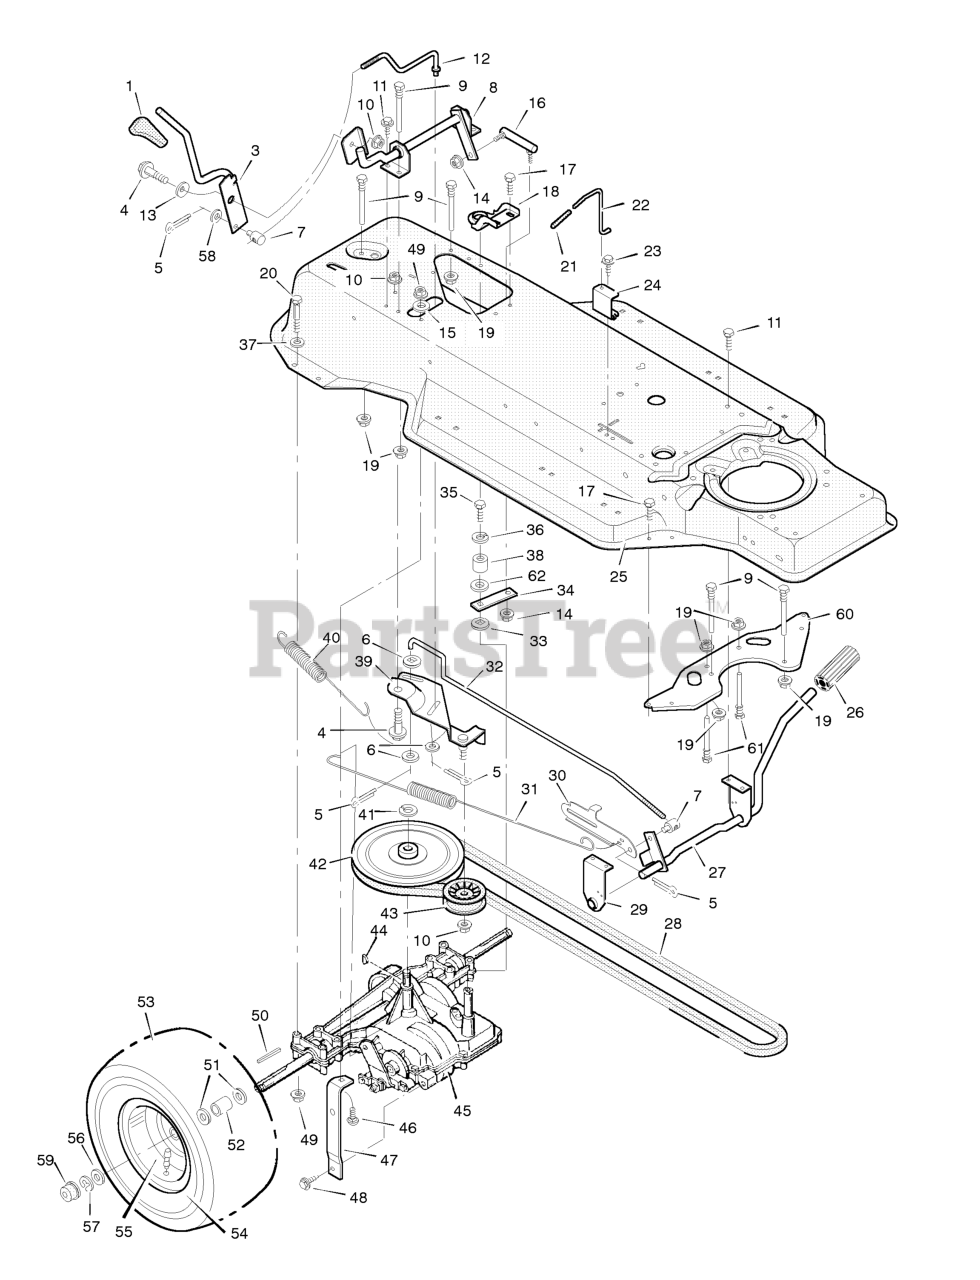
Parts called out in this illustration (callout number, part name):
1	Grip
3	Handle, Shift
4	Bolt, Shoulder
5	Pin, Cotter
6	Washer
7	Nut, Adjustable
8	Shifter Assembly
9	Guide, Belt
10	Locknut, Flange
12	Link, Clutch
13	Washer, Curved
14	Locknut, Flange
16	Link Assembly, Shifter
18	Bracket, Support
19	Nut, Flange
20	Bolt, Hex
22	Rod, Control
24	Guide, Bracket
25	Frame Assembly
26	Pedal, Clutch/Brake
27	Lever Assembly
28	Belt, Motion Drive
29	Bracket, Lever Support
30	Latch, Park Brake
31	Spring, Brake Extension
32	Rod, Clutch
34	Yoke, Shift
35	Bolt, Hex
36	Lockwasher
37	Washer
38	Pilot, Support
39	Bracket Assembly, Idler
40	Spring, Motion Drive
41	Ring, Retainer
42	Pulley, Motion Drive
43	Pulley, Backside Idler
44	Key, Woodruff
45	Transaxle, Peerless **
46	Bolt, Carriage
47	Support, Transaxle
49	Locknut, Flange
50	Key, Square
52	Spacer, Transaxle
53	Tire *
54	Wheel and Tire Assembly
55	Valve Stem
58	Washer
59	Hub Cap
60	Plate, Belt Guide
61	Guide, Belt
